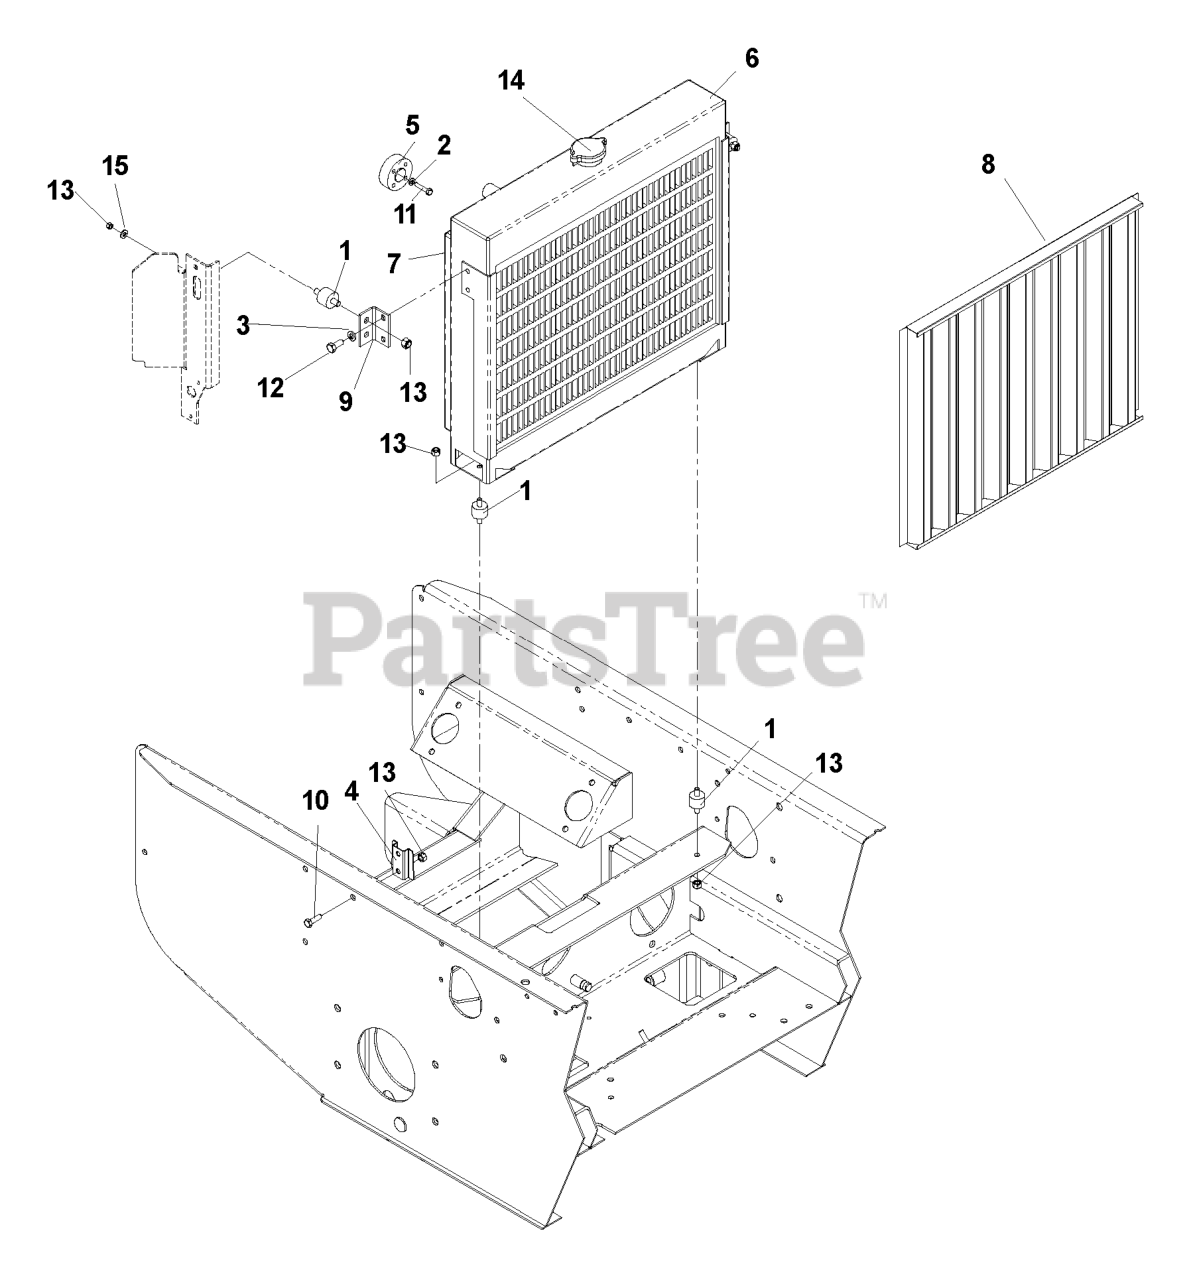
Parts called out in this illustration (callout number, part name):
2	LOCKWASHER 1/4"
3	WASHER.LOCK.HVY.HLCL.SPR.5/16
4	MOUNTING BRACKET
5	FAN SPACER
8	DEBRIS GUARD
9	BRACKET ISO
10	HCS 5/16C X 1
11	BOLT - M6-1.0 X 30MM GR 8
12	HCS 5/16C X 3/4
13	NUT 5/16 NYLOC
14	RADIATOR CAP
15	FLAT WASHER 5/16 SAE
